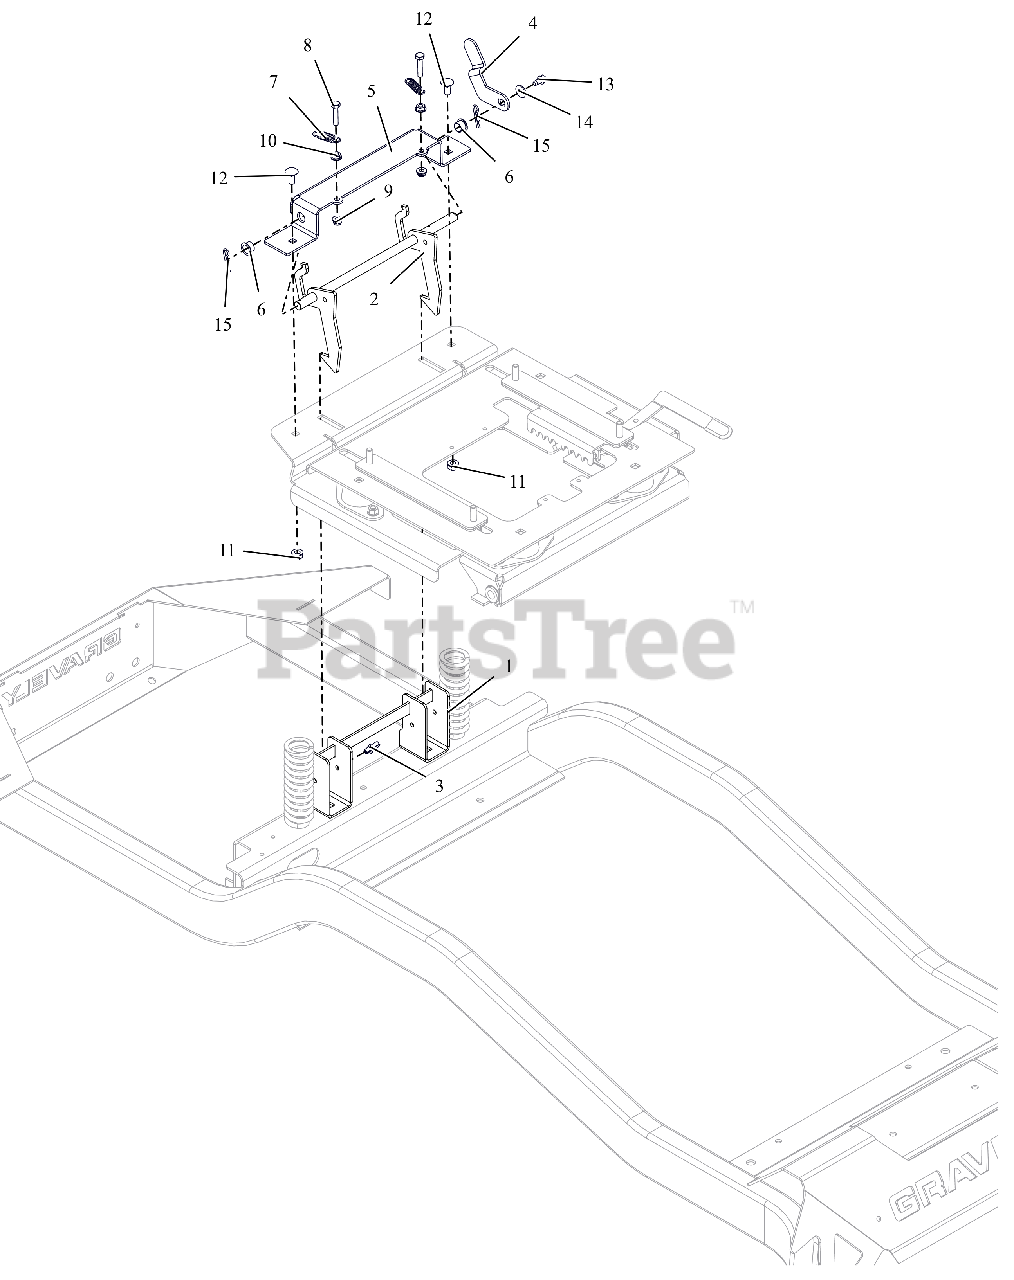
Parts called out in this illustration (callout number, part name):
1	WLDMT, LATCH RECEIVER
2	WLDMT, SEAT
3	ROUTING CLIP (1/2" ID)
4	LEVER, SEAT
5	BRKT, SEAT
6	BUSHING, POLYLINER-.50 SPLIT
7	SG-TENS .063X.44X1.56
8	BLT, HEX .25-20X1.25 G5 ZCC
9	NUT,NYL-FLG .25-20 GF ZCC
10	NUT-SPNLK-FLG .25-20 ZC120
11	NUT,LK-CTR-FLG .31-18 GF ZCC
12	BLT,RHSN .31-18X.75 G5 ZCC
13	SCR-TAP .25-20X.50 HWH ZCC
14	WSHR, FLT .312X.734X.065 ZCC
15	PIN, HAIR-INT .08X.38X1.42 ZCC
